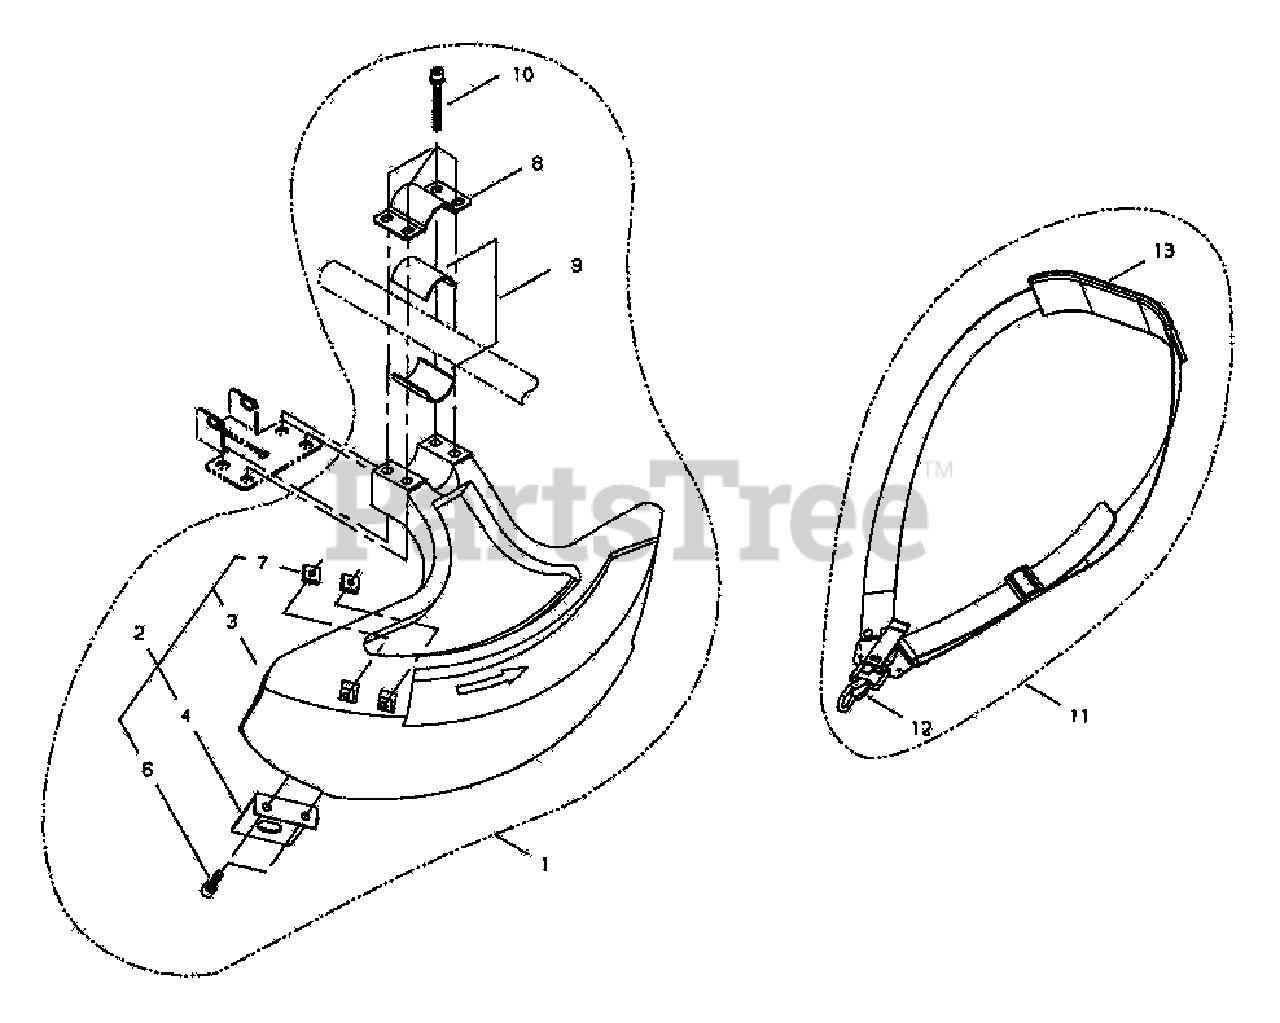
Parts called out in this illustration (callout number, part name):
1	GUARD ASSY
2	DEBRIS SHIELD ASSY
3	SHIELD
4	CUTTER
6	BOLT M5×22
7	NUT M5
8	CLAMP, UPPER
9	SPACER
10	BOLT M5×45
11	HARNESS ASSY, SHOULDER
12	HOOK, SNAP
13	PAD, SHOULDER
